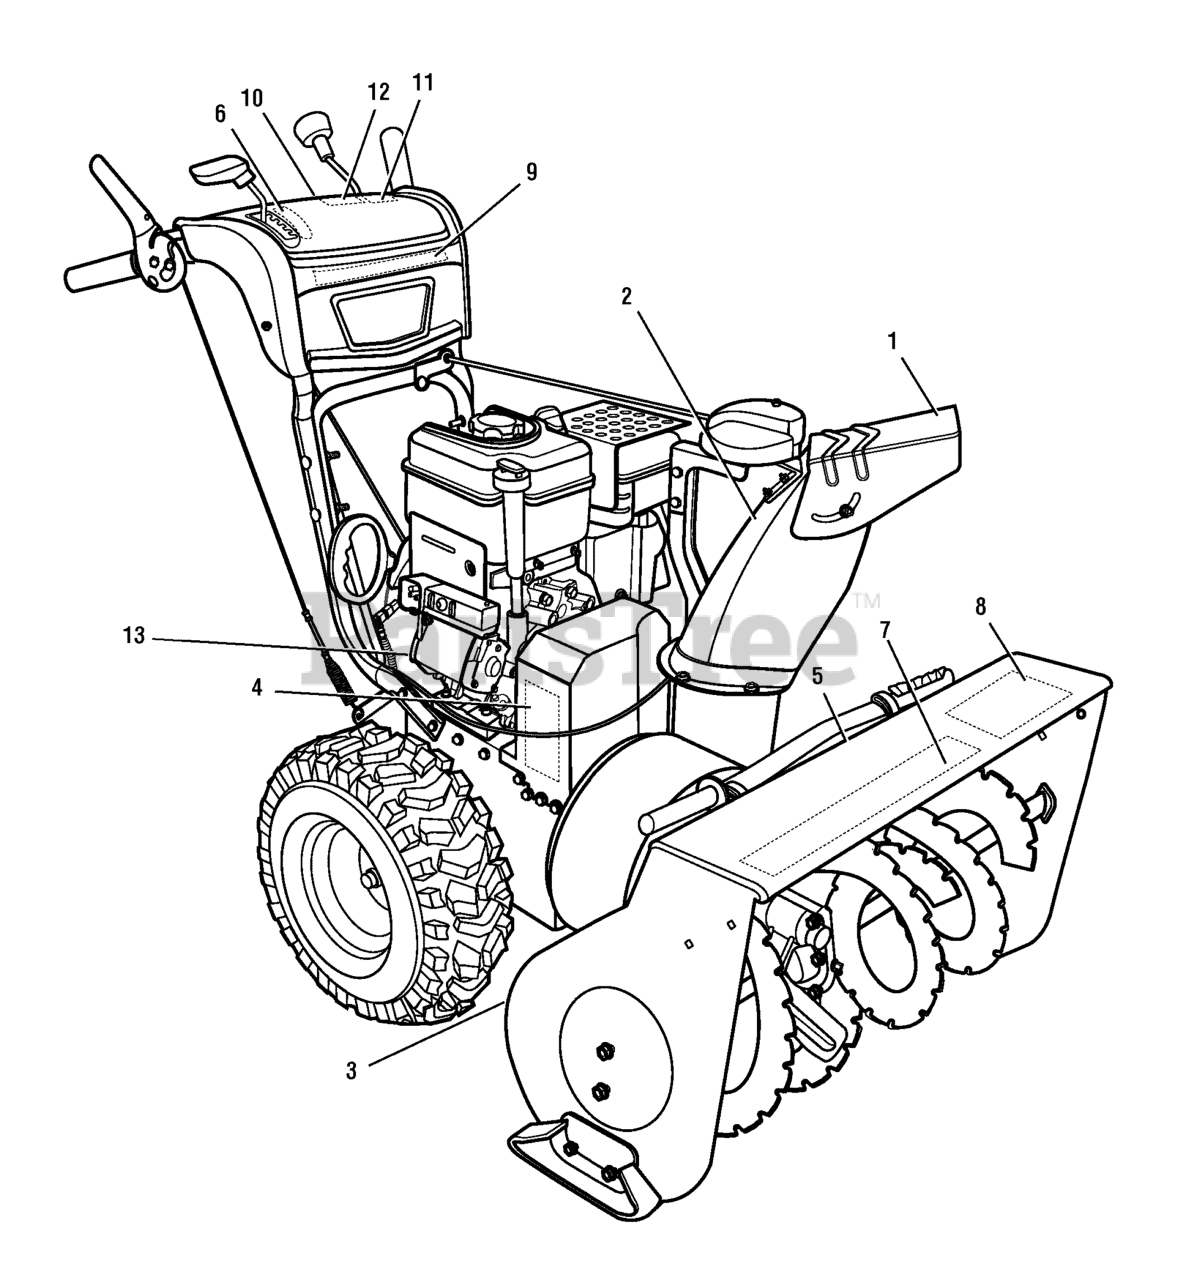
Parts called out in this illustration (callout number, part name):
1	DECAL, THOWN OBJECTS
2	DECAL, DANGER CHUTE
3	DECAL, ISO AUGER FR/EN
4	DECAL, BELT STRETCH
5	DECAL, THROWN OBJECTS
6	DECAL, SHIFT
7	DECAL, BRUTE AUGER
8	DECAL, BRUTE 27"
9	DECAL, BRUTE DASH
10	DECAL, LUBRICATION
11	DECAL, MAIN DASH
12	DECAL, DANGER WARNING
13	DECAL, Over Adjustment of Friction Disc
